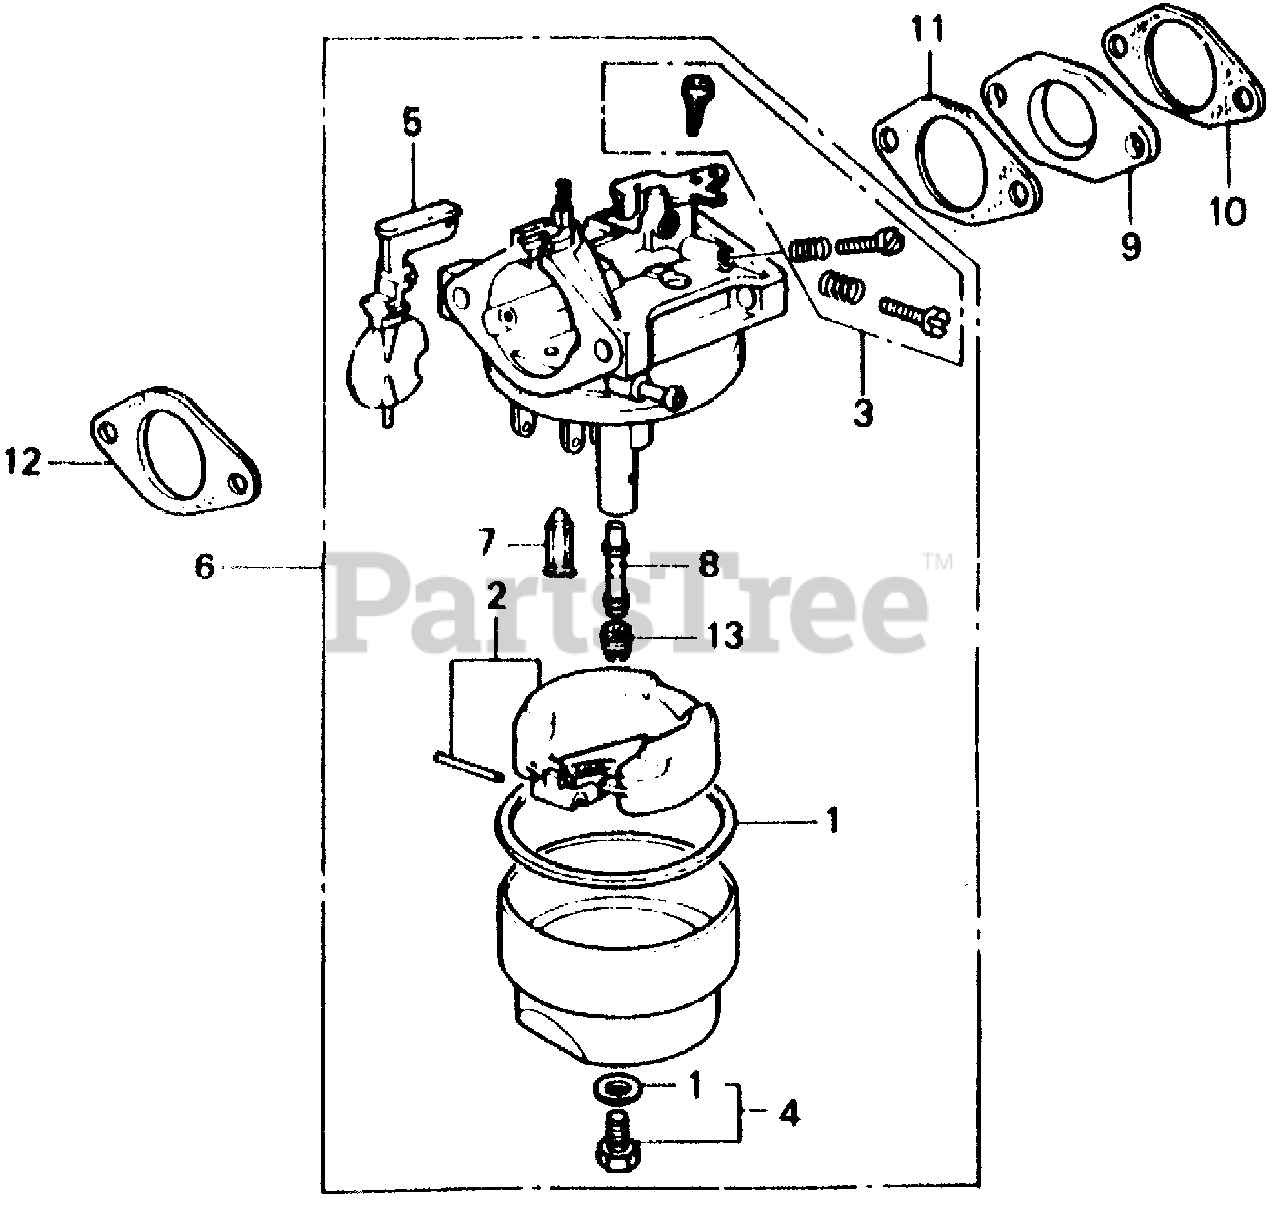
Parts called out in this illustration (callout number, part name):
1	GASKET SET
3	SCREW SET A
4	SCREW SET B
6	CARBURETOR ASSY.
6	CARBURETOR ASSY. (BB28B A/B)
7	VALVE, FLOAT
8	NOZZLE, MAIN
9	INSULATOR, CARBURETOR
10	GASKET, INSULATOR
11	GASKET, CARBURETOR
12	GASKET, AIR CLEANER
13	JET, MAIN (#55)
13	JET, MAIN (#58)
13	JET, MAIN (#60)
13	JET, MAIN (#65)
